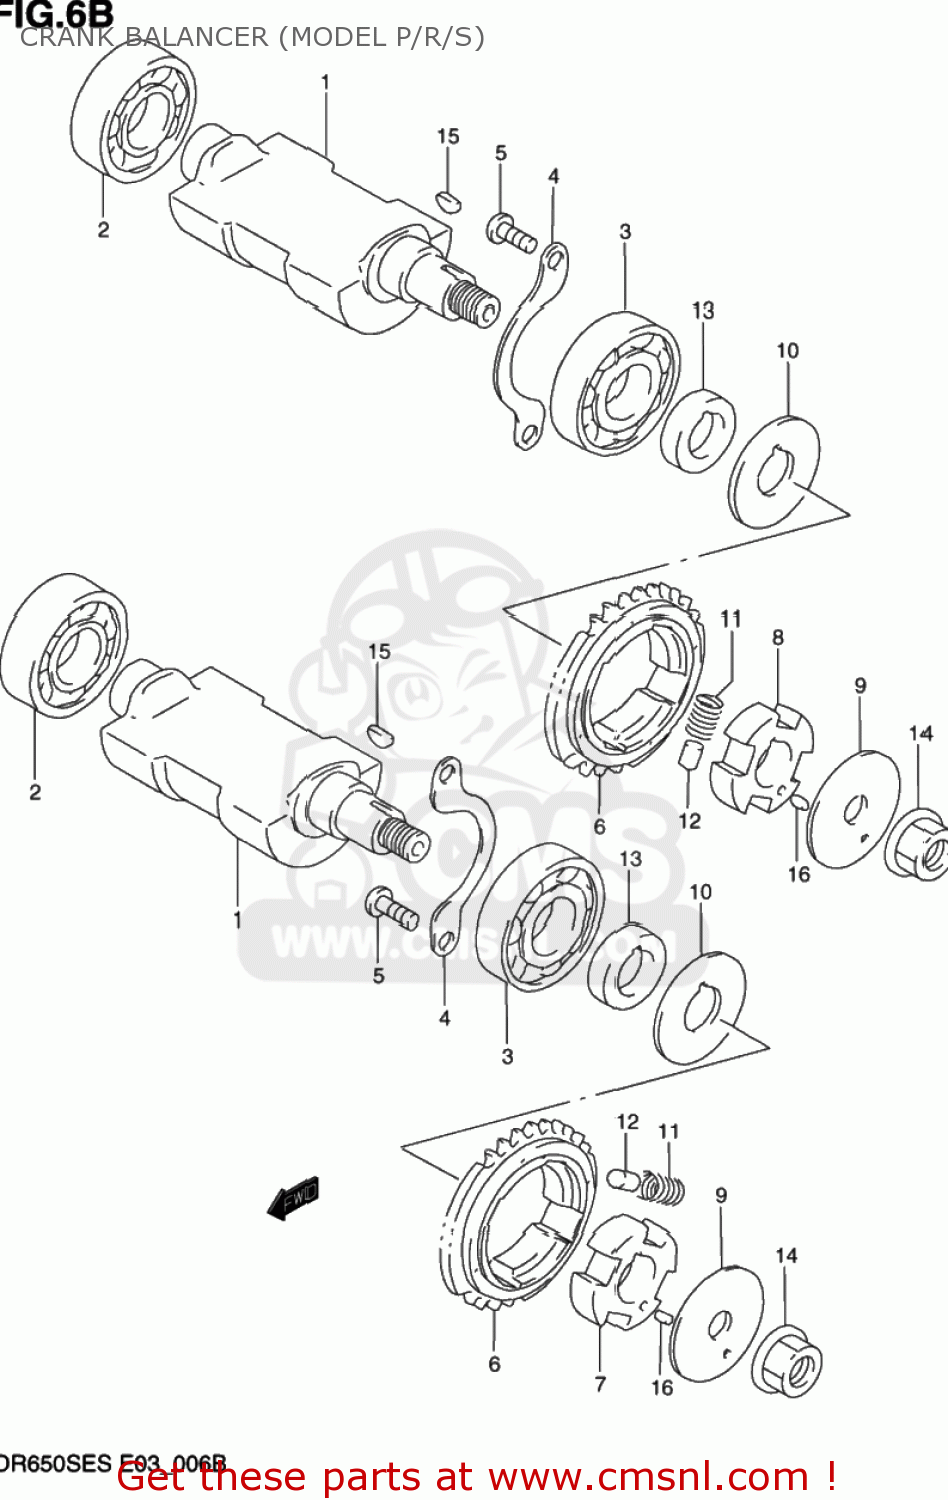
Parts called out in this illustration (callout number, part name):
1	BALANCER,CRANK
2	BEARING(20X42X12)
3	BEARING(20X47X12)
4	RETAINER,CRANK BAL BEARING
5	SCREW
6	SPROCKET,BALANCER DRIVE
7	RACE,CRANK BALANCER
8	RACE,INNER REAR
9	WASHER (10X39X1.6)
10	WASHER
11	SPRING
12	PIN(6X8.8)
13	SPACER (16X26X7.5)
14	NUT (M10X1.25X9)
15	KEY
16	PIN(3X11.3)
